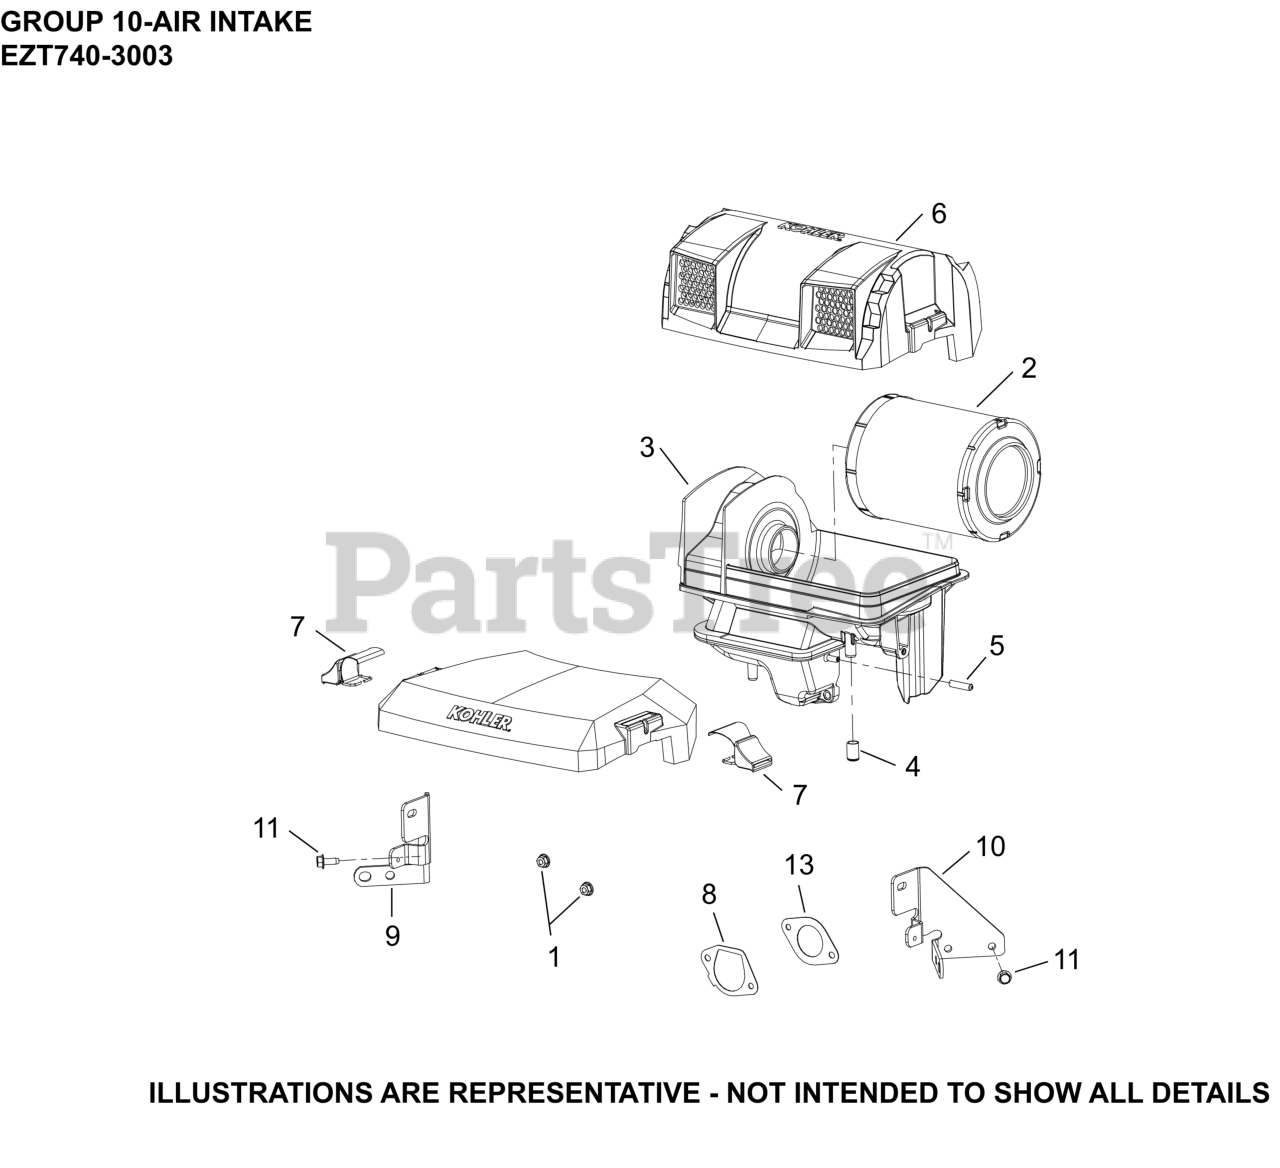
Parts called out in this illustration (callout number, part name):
1	NUT, FLG M6X1.0
2	ELEMENT, AIR FILTER
3	BASE ASSEMBLY, AIR CLEANER (HDAC)
4	CAP, MASKING
5	CAP, MASKING
6	COVER, AIR CLEANER (HDAC)
7	LATCH ASSY, AIR CLEANER COVER
8	GASKET, AIR CLEANER BASE
9	BRACKET, AIR CLEANER BASE (#1 SIDE)
10	BRACKET, AIR CLEANER BASE (#2 SIDE)
11	SCREW, THREAD FORMING
13	GASKET, THROTTLE BODY
NI	ELEMENT, PRE-CLEANER
NI	SCREW, HI-LOW
